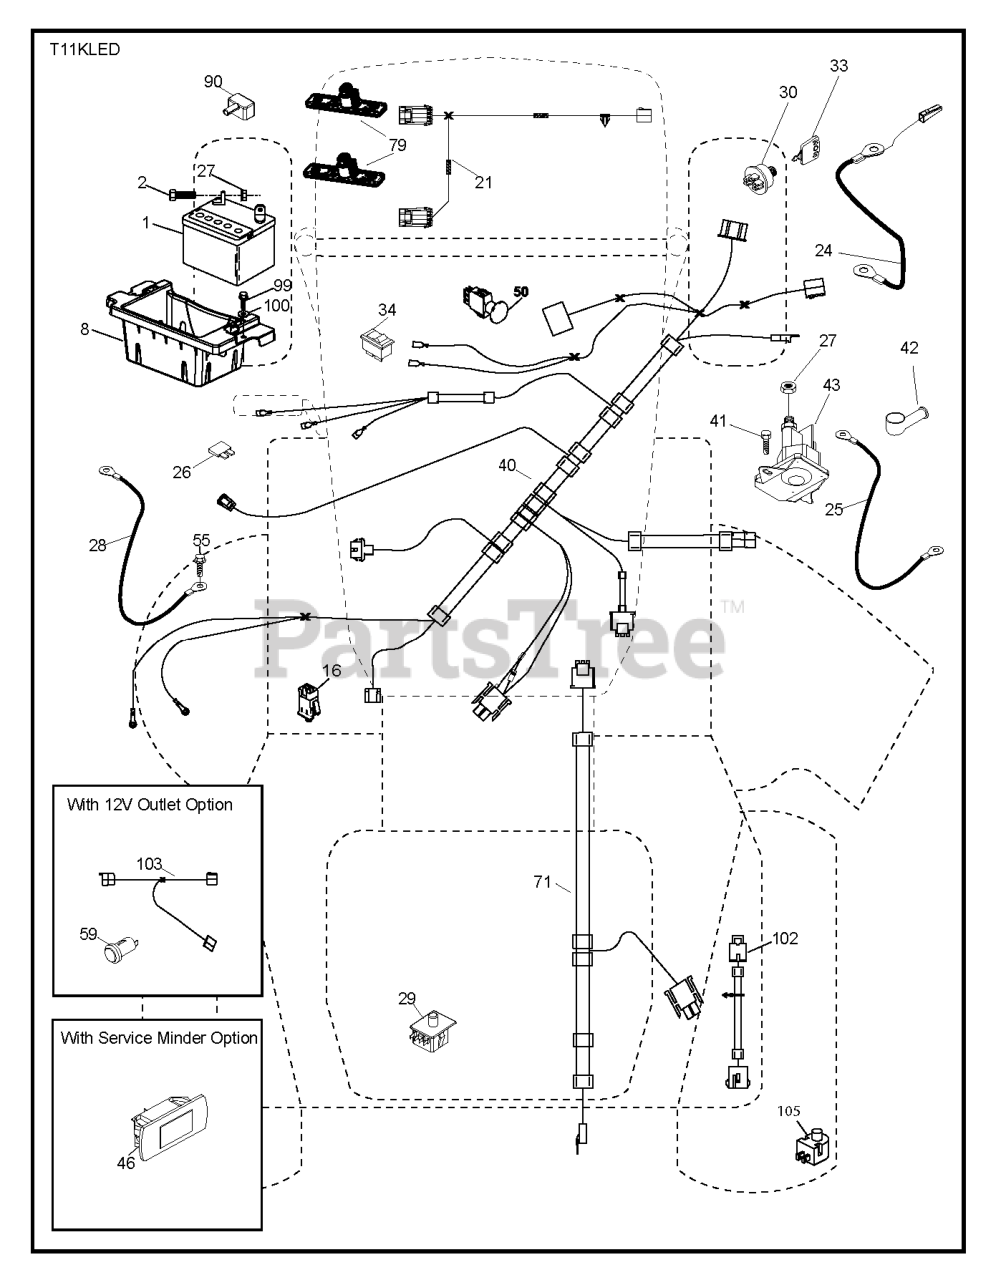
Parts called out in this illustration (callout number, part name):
1	Battery 12 Volt 25 Amp
2	BOLT.HEX.1/4.X.3/4.DICHROMATE
8	TRAY.ASM.BATTERY.FRT.TEX.CARB
16	SWITCH INTERLOOK PUSH-IN
24	CABLE.FRBATT.W/WIRE.8GA.8
25	CABLE.STARTER.8GA.17.5
26	FUSE 20AMP
28	CABLE.GROUND.21"BLK.8GA.90T
29	SWITCH.SEAT.DP W/RAMPS
30	SWITCH.IGN.DELTA.W.LGH.ROS
33	KEY.CHAIN.BLISTER.PACK.GEN.USA
40	HARNESS HARNESS..DASH.ING.ELEC
41	SCREW
42	TERMINAL COVER
46	GUAGE.SRVCMNDR.HRMTR.
50	RP SWITCH.PTO.TERMINAL.STD.RED
55	SCREW 5/16"
71	HARNESS-CHASSIS SUB
90	COVER.TERMINAL.BATTERY
99	SCREW HEXWSHR 1/4-20X3/4
102	HARNESS PIGTAIL PCH TEX ROS
105	REVERSE SWITCH
